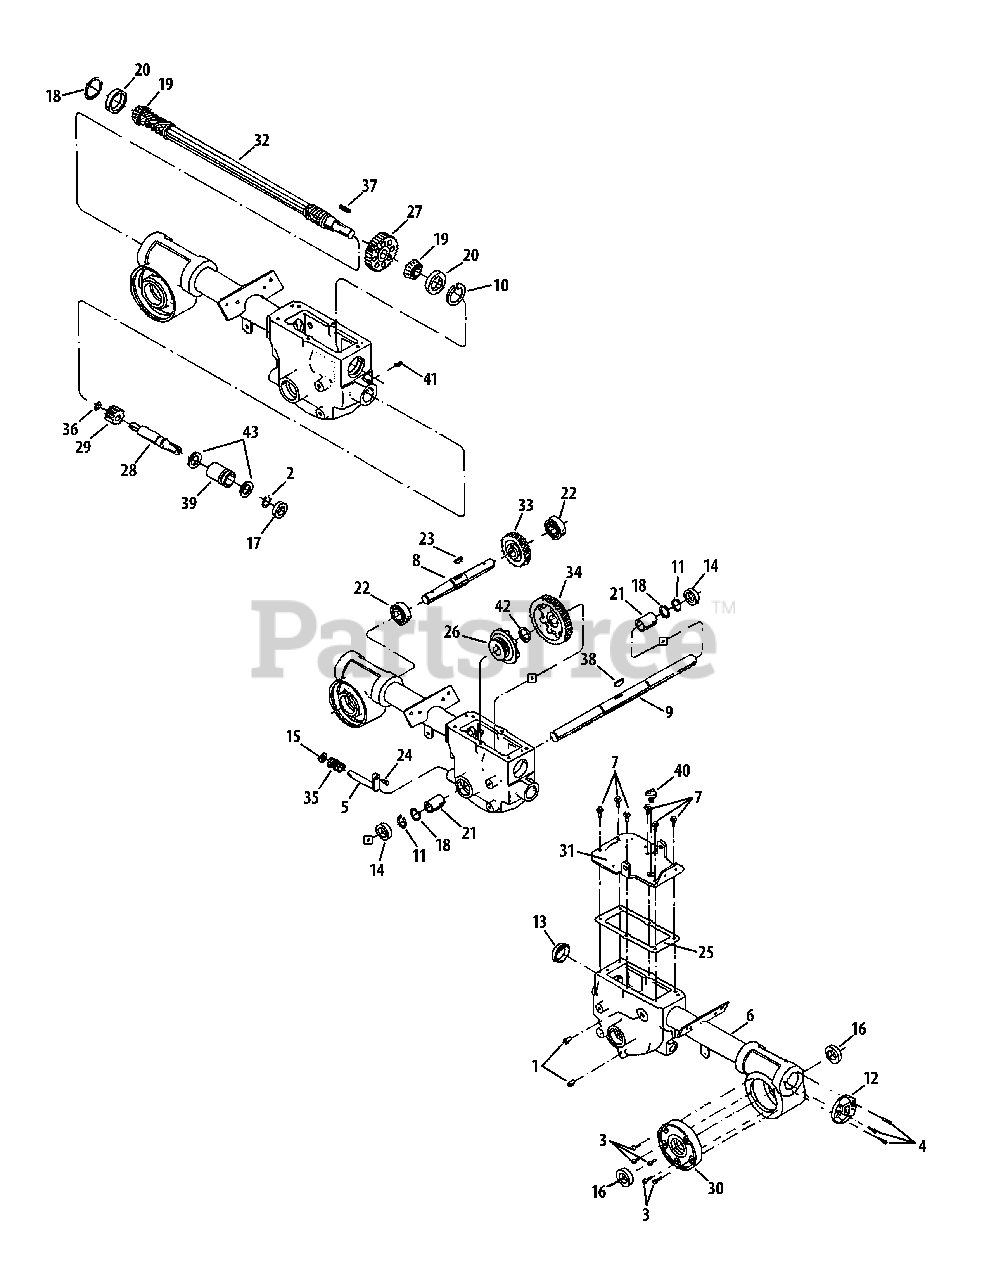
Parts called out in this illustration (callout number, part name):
1	Pipe Plug
2	Retaining Ring
3	Hex Screw, 1.4-20 x .625
4	Self-Sealing Screw, 1.4-20 x .875
5	Eccentric Shaft
6	Transmission Housing
7	Hex Flange Screw, 5.16-18 x .750
8	Tiller Shaft
9	Wheel Shaft
10	Retaining Ring
11	Retaining Ring
12	Rear Bearing Cover
13	Oil Seal, 1.79 x .25
14	Oil Seal, 1.0 x 1.499
15	Oil Seal, .625 x 1.0
16	Oil Seal, .984 x 1.75
17	Oil Seal, .750 x 125
18	Washer, 1.375 x 1.015 x .01
18	Washer, 1.375 x 1.015 x .015
18	Washer, 1.375 x 1.015 x .03
18	Washer, 1.75 x 1.5 x .062
18	Washer, 1.75 x 1.5 x .005
18	Washer, 1.75 x 1.5 x .03
18	Washer, 1.75 x 1.5 x .01
18	Washer, 1.375 x 1.015 x .062
19	Cone Bearing
20	Cup Bearing
21	Bushing, 1.25 x 1 x .005 x 1.5
22	Ball Bearing
23	Woodruff Key, .25 x 1.12
24	Pin, .375 x .72
25	Transmission Cover Gasket
26	Wheel Drive Clutch
27	Spur Gear
28	Pinion Shaft
29	Pinion Gear
30	Housing Cover
31	Transmission Cover
32	Drive Shaft
33	Worm Gear
34	Wheel Drive Gear
35	Spring, .850 x .875
36	Bowed Ring
37	Key, .188 x 1
38	Hi-Pro Key, .25 x 1.312
39	Bushing, 1.24 x .75 x .18
41	Hex Screw, 5.16-18 x .38
42	Washer, 1.46 x 1.016 x .062
43	Washer, 1.022 x .75 x .059
